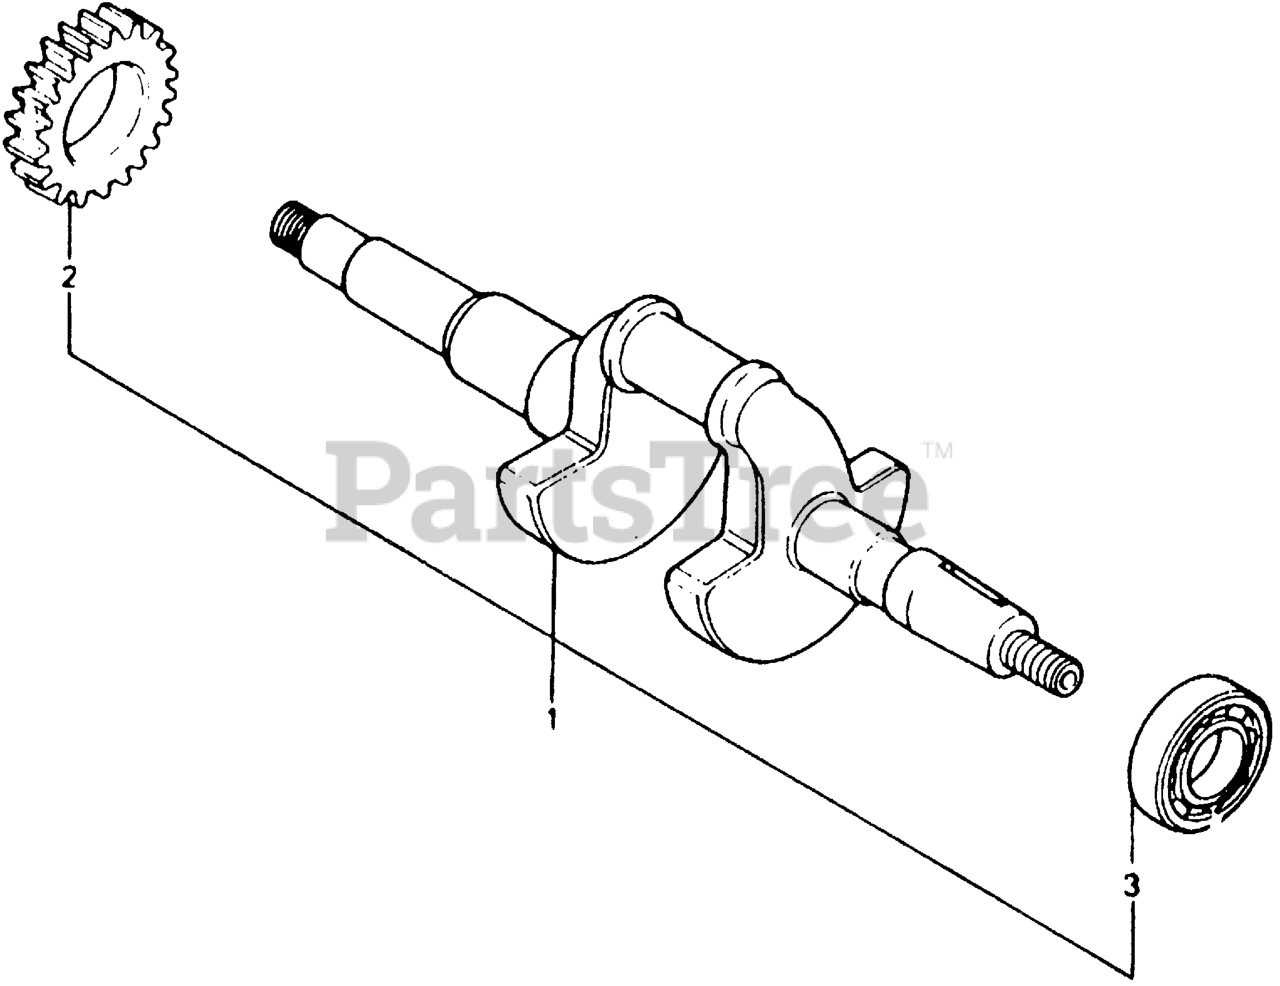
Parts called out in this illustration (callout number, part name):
1	CRANKSHAFT (W-TYPE)
2	GEAR, TIMING
3	BEARING, RADIAL BALL (6205)
